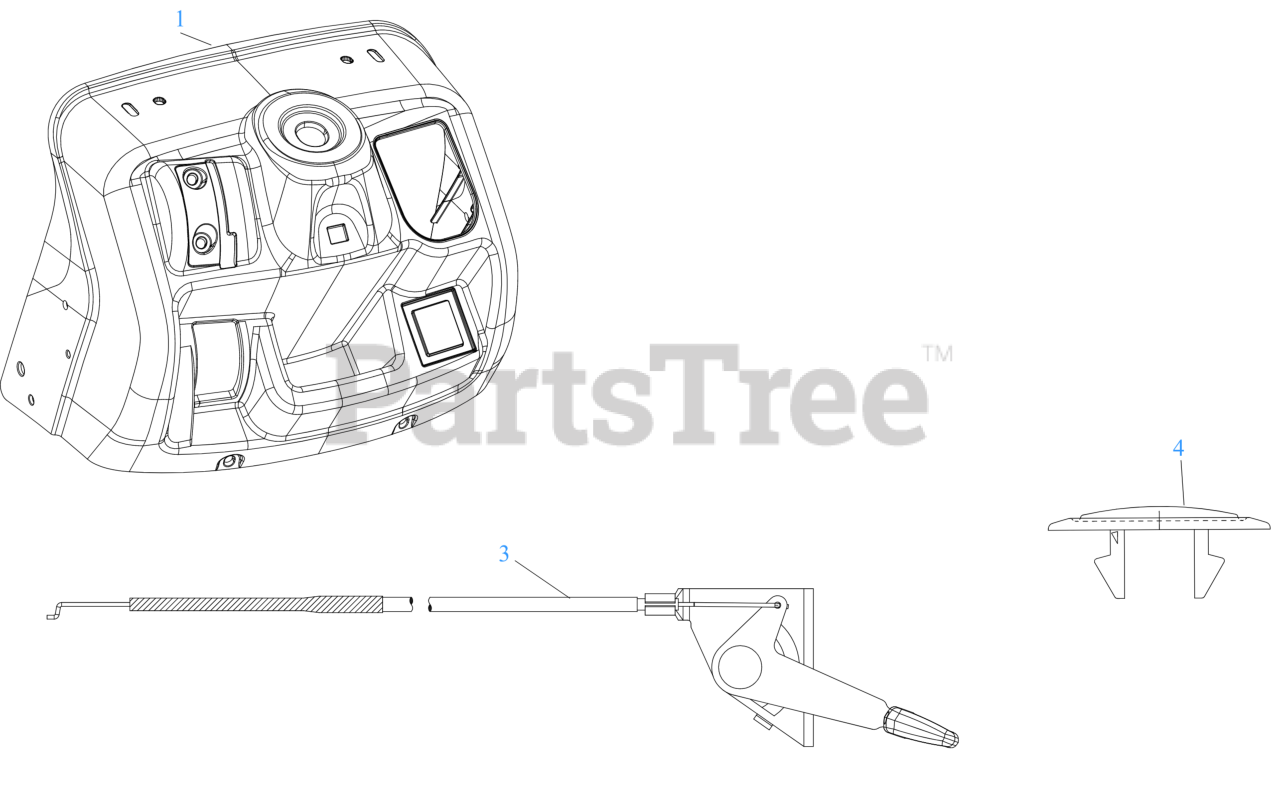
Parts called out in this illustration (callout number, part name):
1	UPPER DASH
3	THROTTLE CABLE 28" x 1.1
4	CHOKE PLUG
